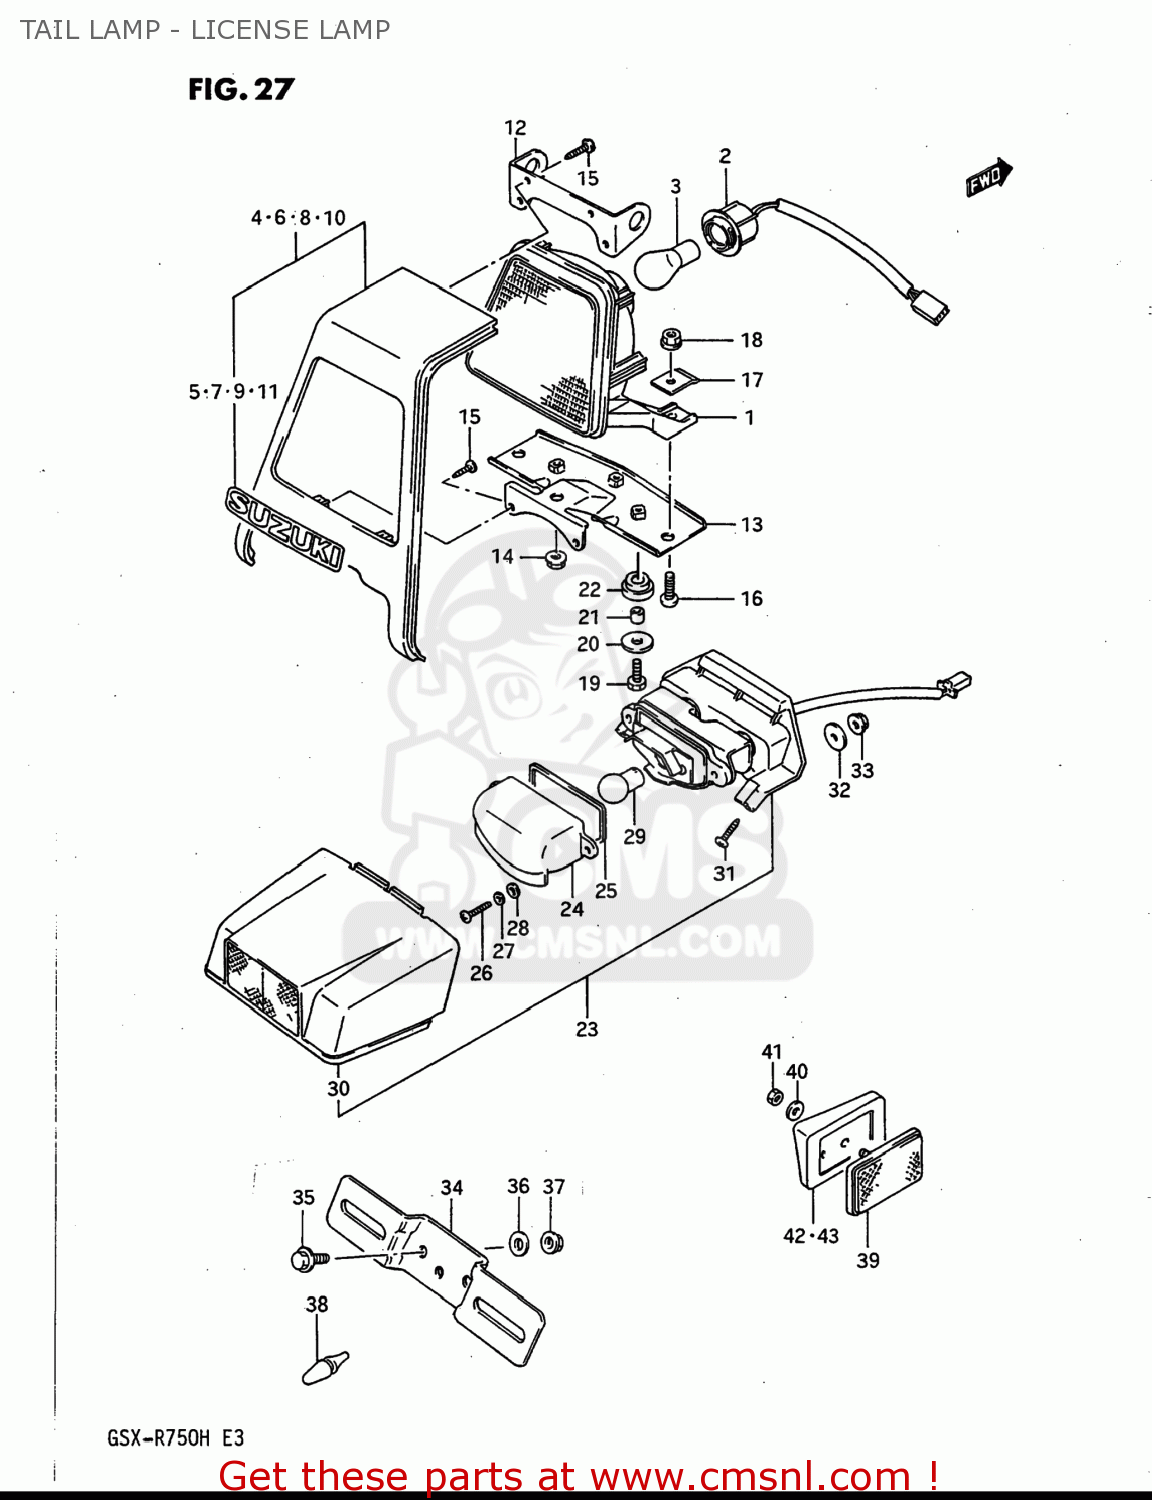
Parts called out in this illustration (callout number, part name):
1	LAMP UNIT
2	SOCKET & CORD ASSEMBLY
3	BULB(12V23/8W,TOKAI DENSO)
4	COVER,TAIL LAMP
5	EMBLEM
6	COVER,TAIL LAMP
7	EMBLEM
8	COVER,TAIL LAMP
9	EMBLEM
10	COVER,TAIL LAMP
11	EMBLEM
12	PLATE
13	BRACKET
14	NUT
15	SCREW
16	SCREW
17	PLATE,TAIL LAMP
18	NUT
19	BOLT,M6X1X20
20	WASHER
21	SPACER (6.1X9X7.5)
22	CUSHION
23	LAMP ASSEMBLY,LICENSE
24	LENS,LICENSE LAMP
25	GASKET,LICESE LAMP (NAS)
26	SCREW
27	WASHER,LOCK 4M
28	WASHER 4MM
29	BULB
30	COVER,LICENSE LAMP
31	SCREW
32	WASHER (5.5X20X1.2)
33	NUT
34	BRACKET,LICENSE PLATE
35	BOLT
36	WASHER
37	NUT
38	CUSHION
39	REFLECTOR,REFLEX
40	WASHER(5.2X16X1)
41	NUT ,5MM
42	SPACER,REAR SIDE,REAR,RIGHT
43	SPACER,REAR SIDE,REAR,LEFT
